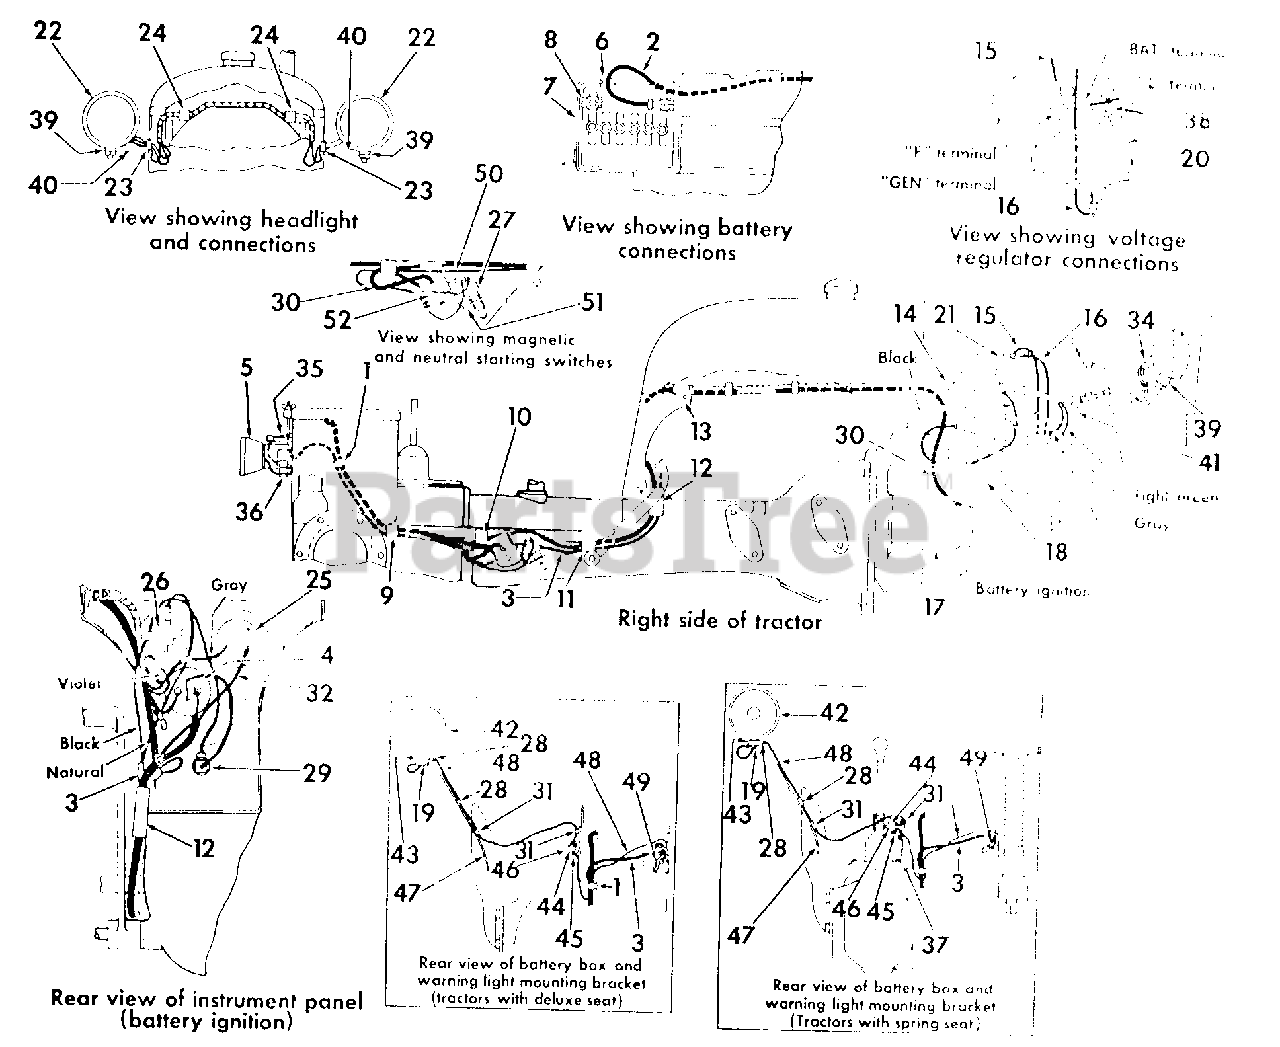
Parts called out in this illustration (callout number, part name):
1	STRAP, CABLE WRAPPING
2	CABLE W/BOLT
3	CABLE ASSY, REAR LIGHT
4	SWITCH ASSY, BATTERY IGNITION KEY
5	LIGHT ASSY, TAIL
6	GROMMET, BATTERY BOX
7	BATTERY -12 VOLT-
8	STRAP W/BOLT, IH-356062-R91, BATTERY TO GROUND
9	CLIP, CABLE
10	CLIP, THIRD BOLT FROM REAR
11	STRAP, CABLE WRAPPING
12	CLIP, INSIDE RIGHT SIDE FUEL TANK SUPPORT
13	CLIP CABLE HARNESS -RH SIDE-
14	HARNESS ASSY, CABLE
15	CABLE, GENERATOR -F- TERMINAL TO REGULATOR -F- TERMINAL
16	CABLE, GENERATOR -A- TERMINAL TO REGULATOR -GEN- TERMINAL
17	MOTOR ASSY, CRANKING
18	BATTERY IGNITION UNIT
19	CLIP FLASHING WARNING LIGHT CABLE
20	REGULATOR ASSY, VOLTAGE
21	GENERATOR ASSY
22	LIGHT ASSY, HEAD
23	GROMMET, RUBBER NO. 6 -IN HOOD-
24	CLIP, HEAD LIGHT CABLE HARNESS
25	INDICATOR ASSY, CHARGE
26	SWITCH ASSY, LIGHTING
27	SWITCH ASSY, NEUTRAL STARTING
28	CLIP, SNAP-ON CABLE
29	HOUSING ASSY, FUSE
30	CABLE ASSY, MAGNETIC SWITCH TO CRANKING MOTOR
31	CLIP, FLASHING WARNING LIGHT CABLE
32	CABLE, MAGNETIC SWITCH TO CHARGE INDICATOR POSITIVE TERMINAL
34	BODY, CONNECTOR
35	CLIP, REAR LIGHT CABLE
36	CLIP, TAIL LIGHT CABLE
37	BRACKET, FLASHER MOUNTING CLAMP
38	BRACKET, VOLTAGE REGULATOR MOUNTING
39	SPACER, HEAD LIGHT
40	POST, HEAD LIGHT
41	CLIP, CABLE HARNESS
42	LIGHT ASSY, FLASHING WARNING
43	GASKET, FLASHING WARNING LIGHT
44	FLASHER ASSY, WARNING LIGHT
45	CLAMP, FLASHER MOUNTING
46	ABSORBER, FLASHER MOUNTING
47	BRACKET, FENDER MOUNTING
48	CABLE ASSY, FLASHER TO LIGHT
49	CABLE, FLASHING WARNING LIGHT TO LIGHTING SWITCH -BLACK-
50	HARNESS ASSY, NEUTRAL STARTING SWITCH
51	BRACKET, NEUTRAL STARTING SWITCH
52	SWITCH ASSY, MAGNETIC
IH-120512HX	BOLT ASSY, TERMINAL
